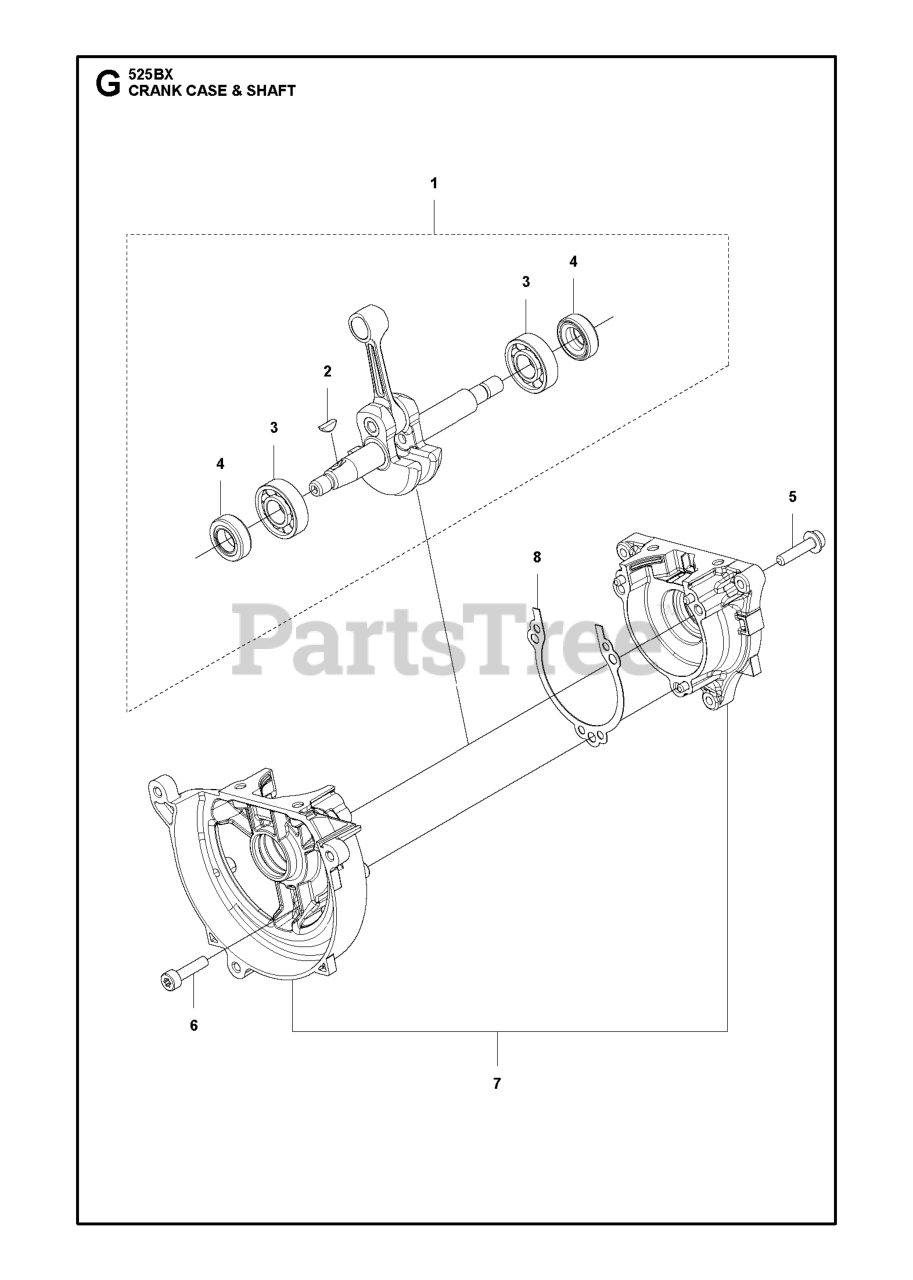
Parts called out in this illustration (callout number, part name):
1	KIT CRANKSHAFT
6	BOLT
7	CRANKCASE COMP
8	GASKET CASE
